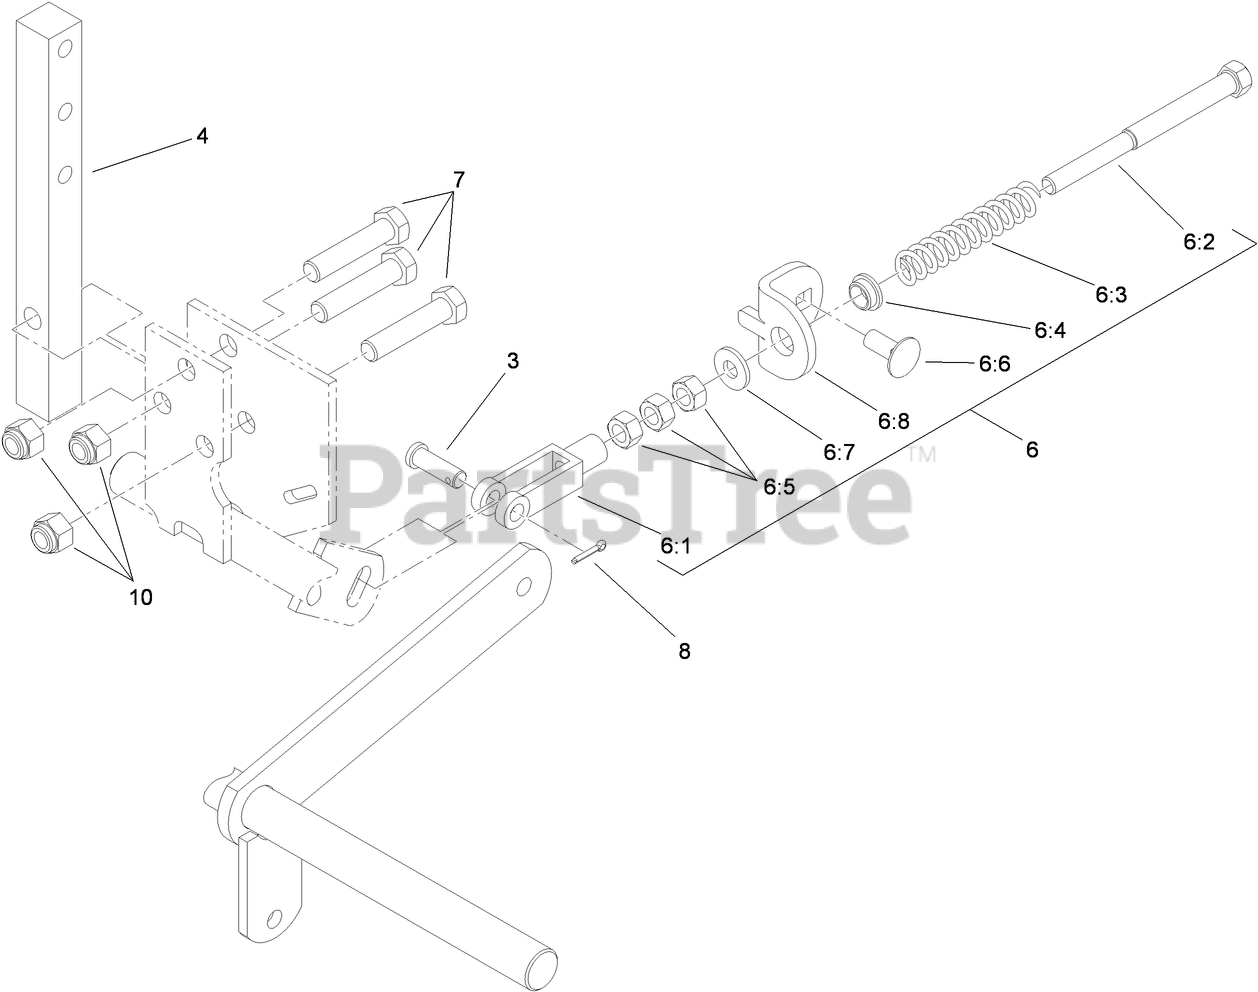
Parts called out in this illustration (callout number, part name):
3	PIN-CLEVIS
4	ARM-SHAFT, CONTROL
6	NEUTRAL RETURN ASM
6:1	YOKE-ADJUSTABLE
6:2	BOLT-RETURN, NEUTRAL
6:3	SPRING-RETURN, NEUTRAL
6:4	BUSHING-NYLON, FLANGED
6:5	NUT-HEX
6:6	SCREW-CARR
6:7	WASHER-FLAT
6:8	TAB-ADJUSTMENT
7	SCREW-HH
8	PIN-COTTER
10	NUT-LOCK, NI
